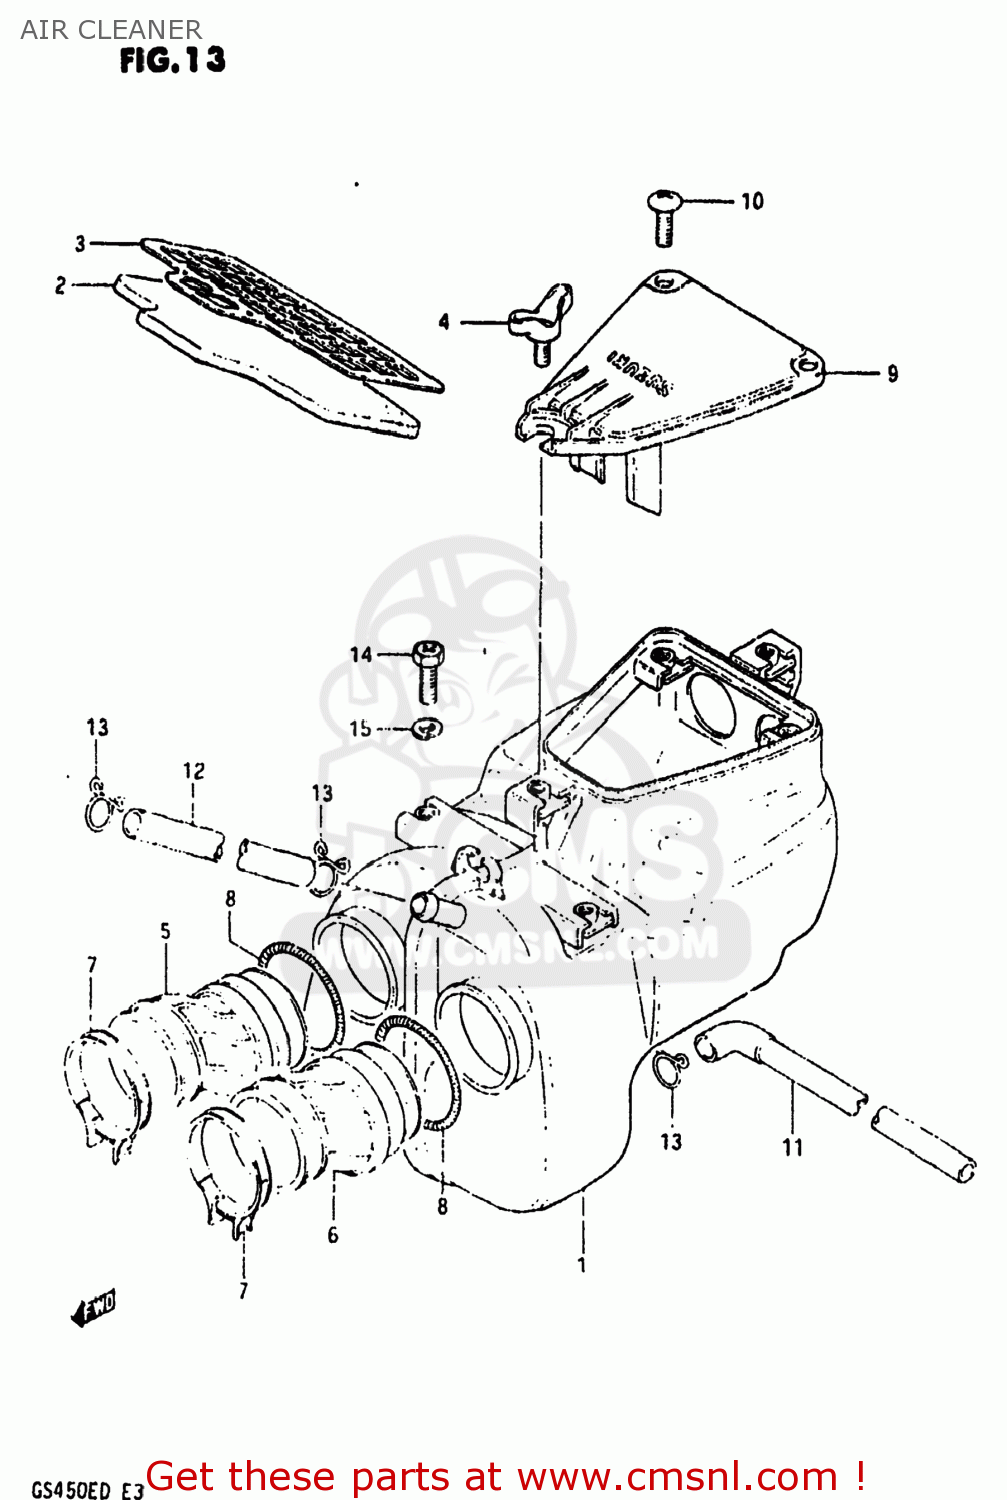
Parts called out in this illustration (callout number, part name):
1	CLEANER ASSEMBLY,AIR
2	FILTER
3	HOLDER,OUTER
4	BOLT, WING
5	TUBE,OUTLET,R
6	TUBE,OUTLET,L
7	CLAMP
8	CLAMP,CLEANER SIDE
9	CAP,AIR CLEANER
10	SCREW
11	DRAIN TUBE
12	TUBE,BREATHER
13	CLAMP
14	BOLT L:16
15	LOCK WASHER
